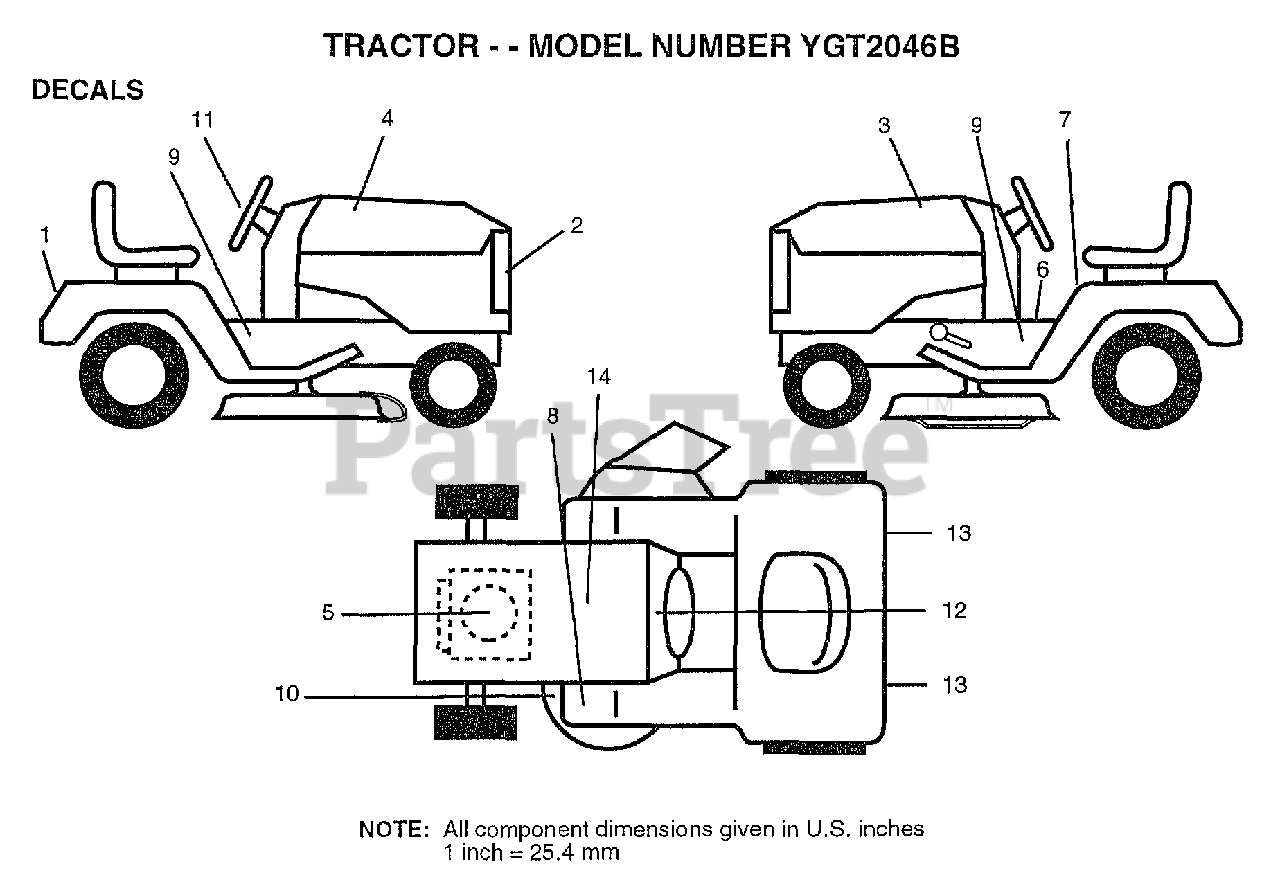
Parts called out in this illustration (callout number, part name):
1	DECAL FENDER
2	DECAL GRILLE
3	DECAL HOOD LH
4	DECAL HOOD RH
5	DECAL, ENGINE
6	DECAL BRAK PARK
7	"DECAL DANGER,FEND"
9	"DECAL CHASSIS,46"""
11	DECAL INS STRG WH
12	"DECAL-OPER,GEAR D"
13	REFLECTOR-TAIL YT
14	DECAL.BATRY.3-3908
